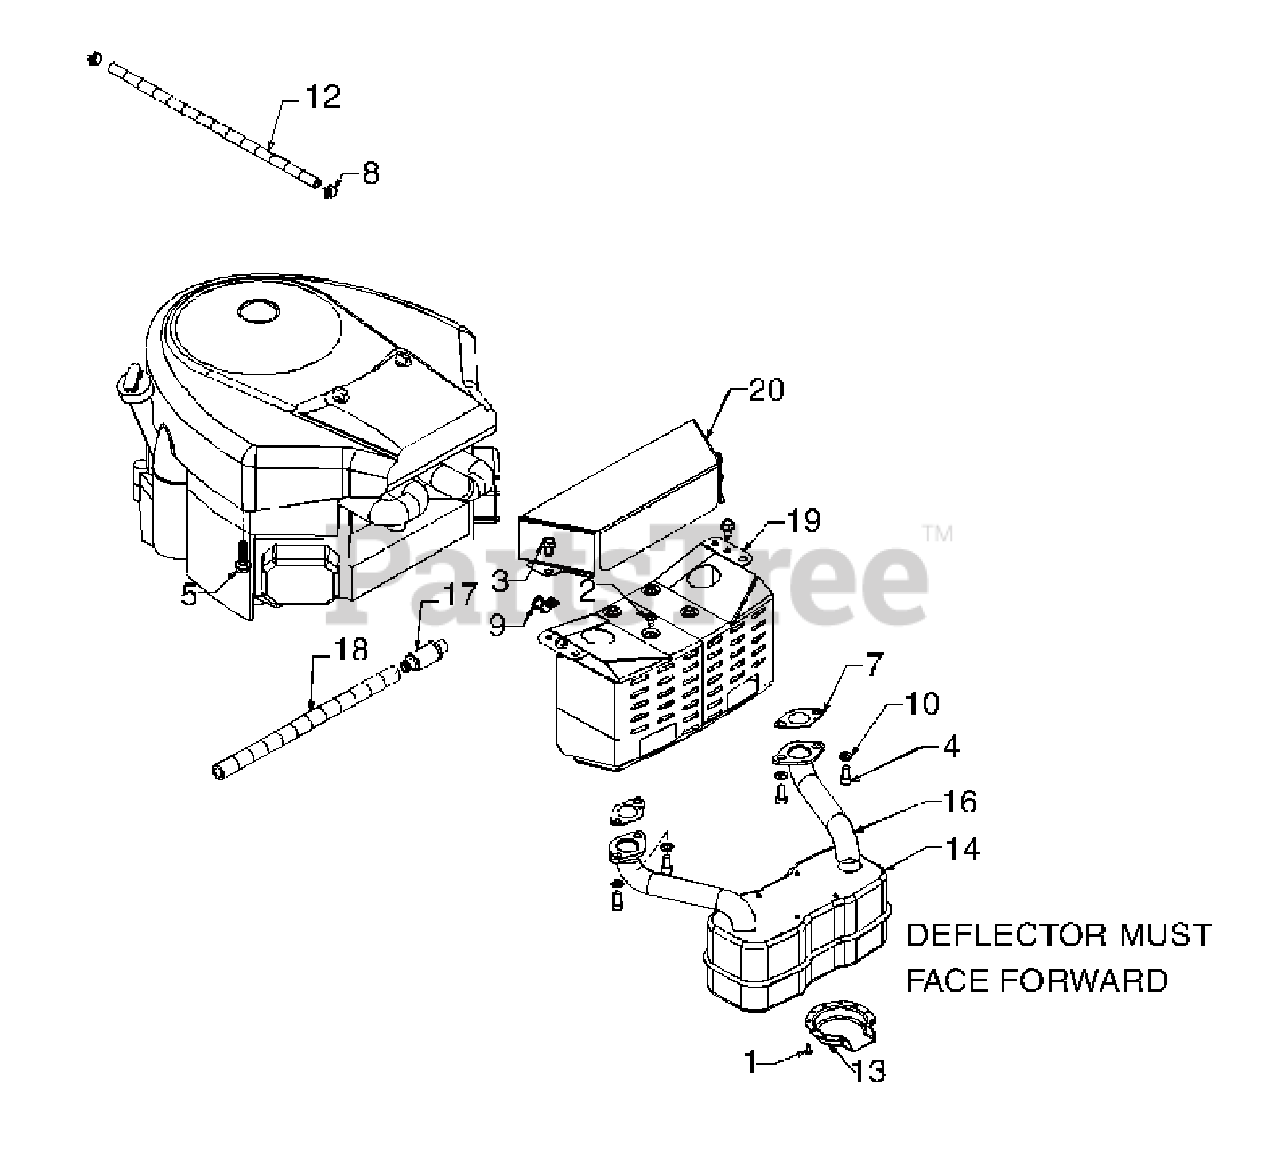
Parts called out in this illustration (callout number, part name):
1	Hex Tap Scr. #8-32 x .38" Lg.
2	Hex Wash. TT-Tap Scr. 1/4-20 x 5" Lg.
3	Hex Wash. TT-Tap Scr. 5/16-18 x .62" Lg.
4	Hex Wash. TT-Tap Scr. 3/8-16 x 1.25" Lg.
5	Scr. 3/8-16 x 1.25 Lg.
7	Exhaust Gasket
10	Lock Washer 5/16 Reg.
12	Hose, Fuel Line
13	Dfl, Muffler
14	Muffler, Twin Inlet
16	Exhaust Tube-L.H.
17	Oil Drain
18	Oil Drain Hose - 12"
20	Heat Shield
